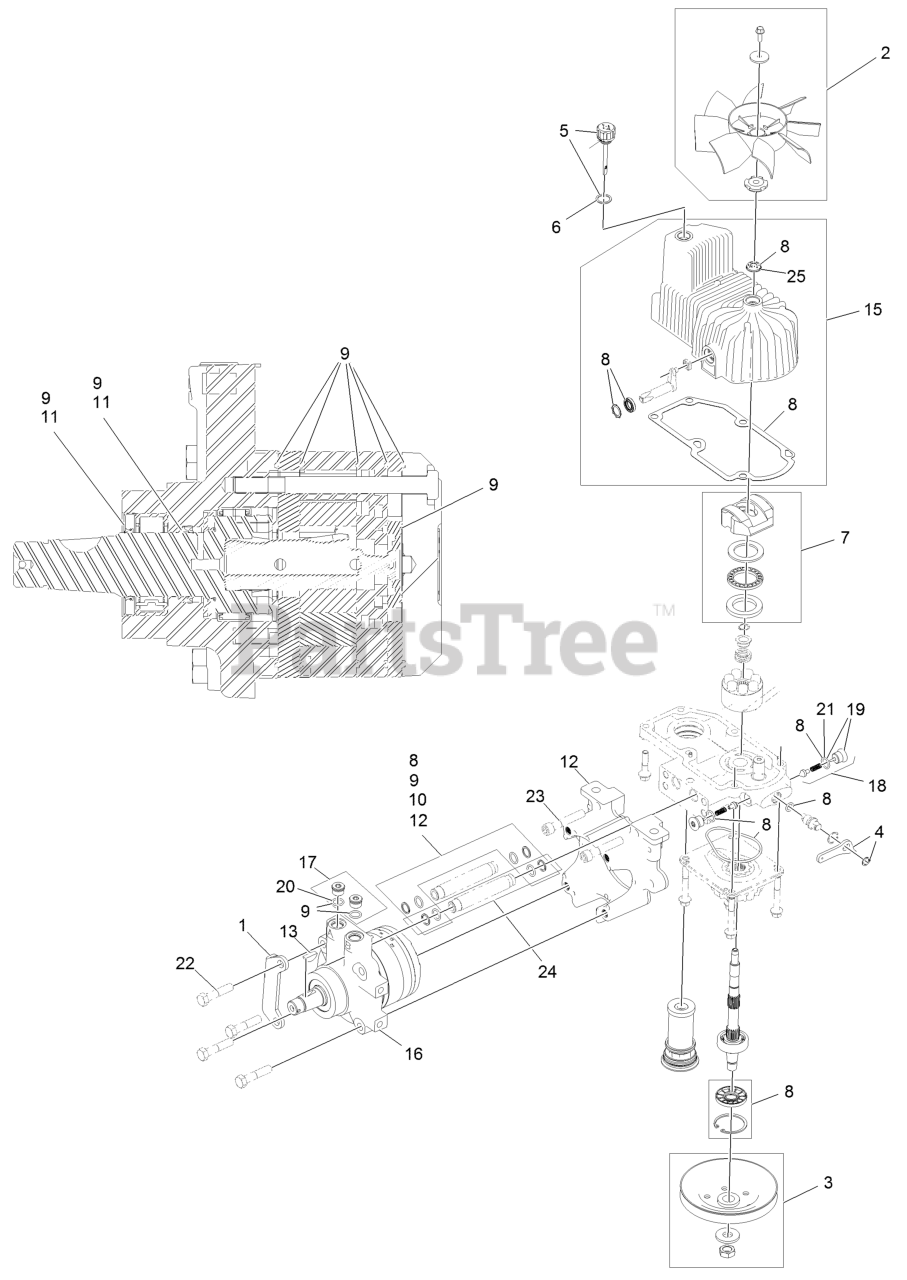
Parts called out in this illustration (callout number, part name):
1	Mount-Shoe, Horse
2	Fan Kit
3	Pulley Kit
4	Handle-Bypass Valve, Hydro
5	Dipstick-Hydro W/Gasket
6	Gasket-Dipstick, Hydro
7	Swash Block Kit
8	Pump Seal Kit
9	Motor Seal Kit
10	Tube Seal Kit
11	Output Shaft Seal Kit
12	Nose Cup-Uht
13	Key-Woodruff 5/16 X 1
15	Housing-RH
16	Motor-Hydraulic RH 240Cc
17	Magnetic Plugs Service Kit
18	Check Valve ASM
19	Plug-Check (W/O-Ring)
21	O-Ring-Check Valve
22	Screw-HH 1/2-20 X 2 1/4
23	Screw-HSH 1/2-20 X 2 3/4
24	Hydraulic Tube Kit
25	Seal-Fan Drive
99	Flow Test Kit
99	Puller-Pulley
